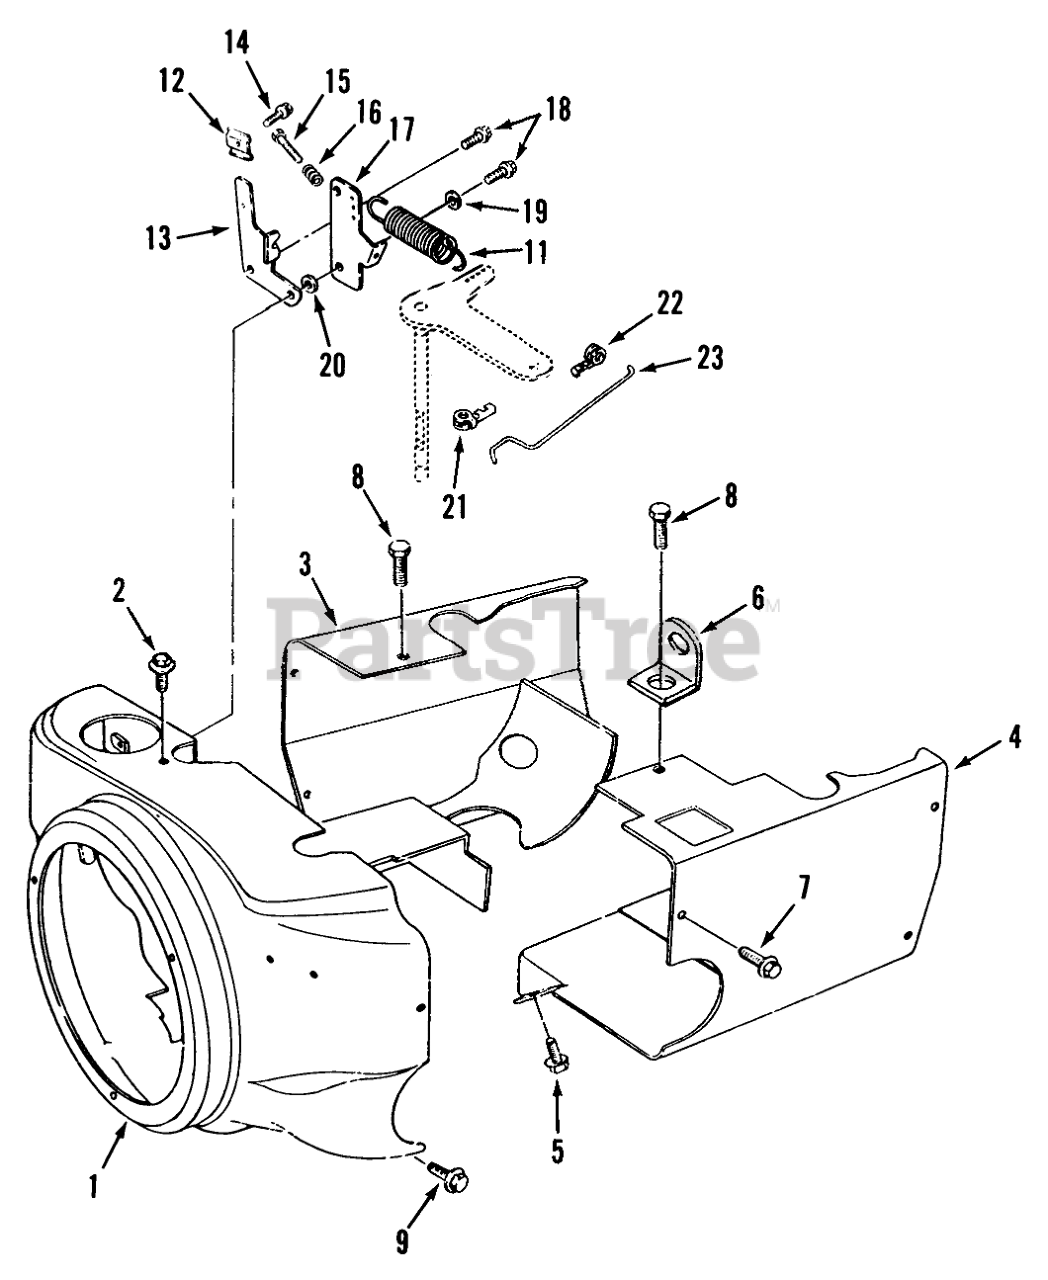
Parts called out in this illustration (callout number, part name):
1	BLOWER HOUSING
3	Cylinder Air Housing LS
4	Cylinder Air Housing
5	Bolt
6	Bracket-Lifting
7	Wash. Hd. Screw 1/4-20 x 1/2
8	Bolt
9	Wash. Hd. Screw 1/4-20 x 1/2
11	Spring
12	Clip
13	CABLE BRACKET
14	Bolt
15	HH ST SCREW
16	Spring
17	GOVERNOR CONTROL ARM
18	Bolt
19	Screw
20	Bushing
21	Clip-Retaining
22	Retaining Clip
23	GOVERNOR CONTROL ROD
